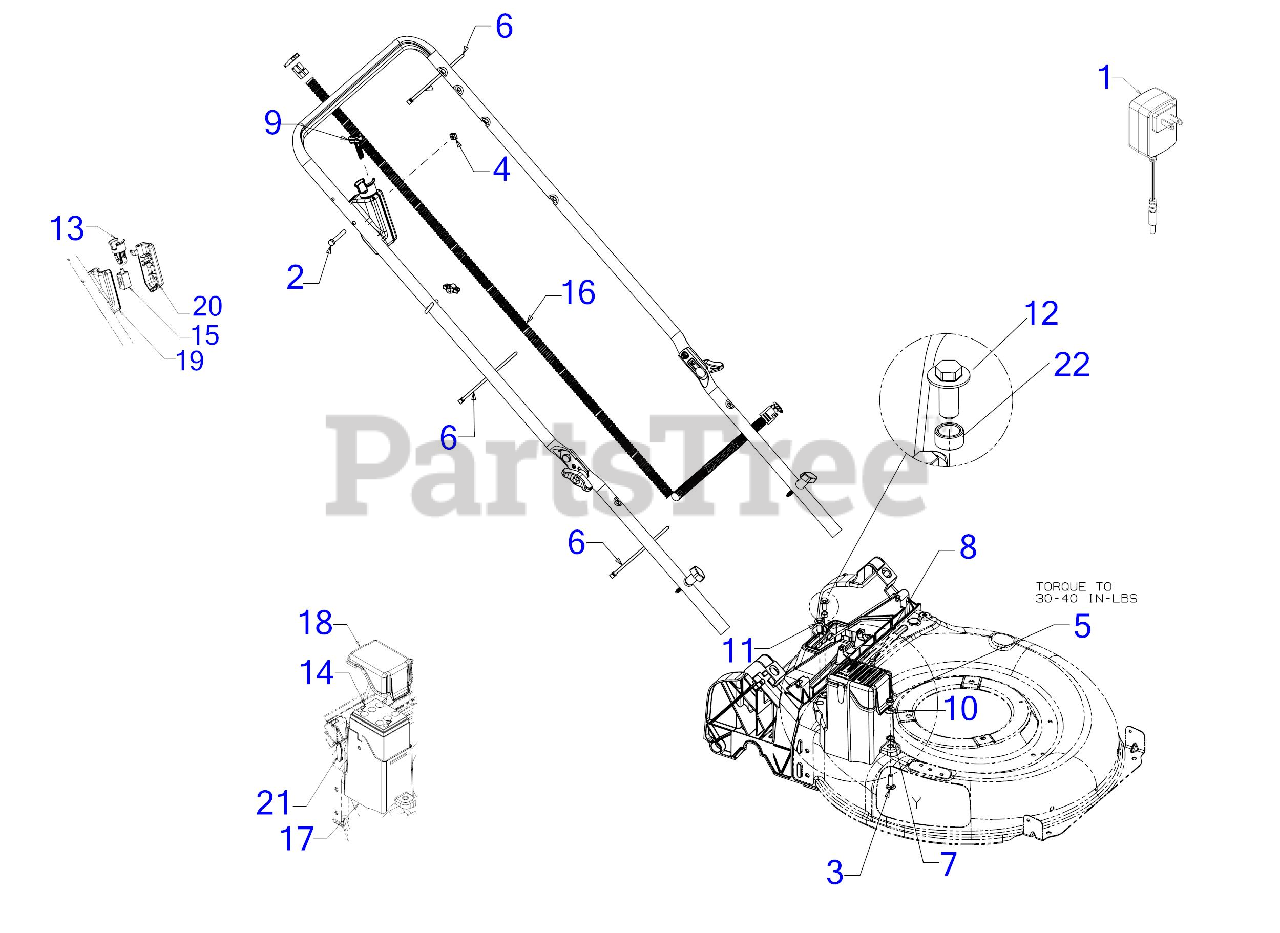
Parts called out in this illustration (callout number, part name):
1	BATTERY CHARGER
2	HEX SCREW 1/4-20 x 1.75
3	CARRIAGE BOLT 5/16-18 x 1.00
4	SQUARE NUT 1/4-20
5	HEX NUT
6	7" CABLE TIE
8	36" CABLE TIE
10	BELL WASHER .337 X.867 x .057
11	SHOULDER SCREW 5/16-14 x .972
12	SCREW 5/16-14 x .750
13	KEY SWITCH ASSEMBLY
14	BATTERY 12V
15	PLUNGER SWITCH 20A
17	BATTERY HOUSING
18	TOP BATTERY HOUSING
19	PUSH START HOUSING (RH)
20	PUSH START HOUSING (LH)
21	LID SEAL
